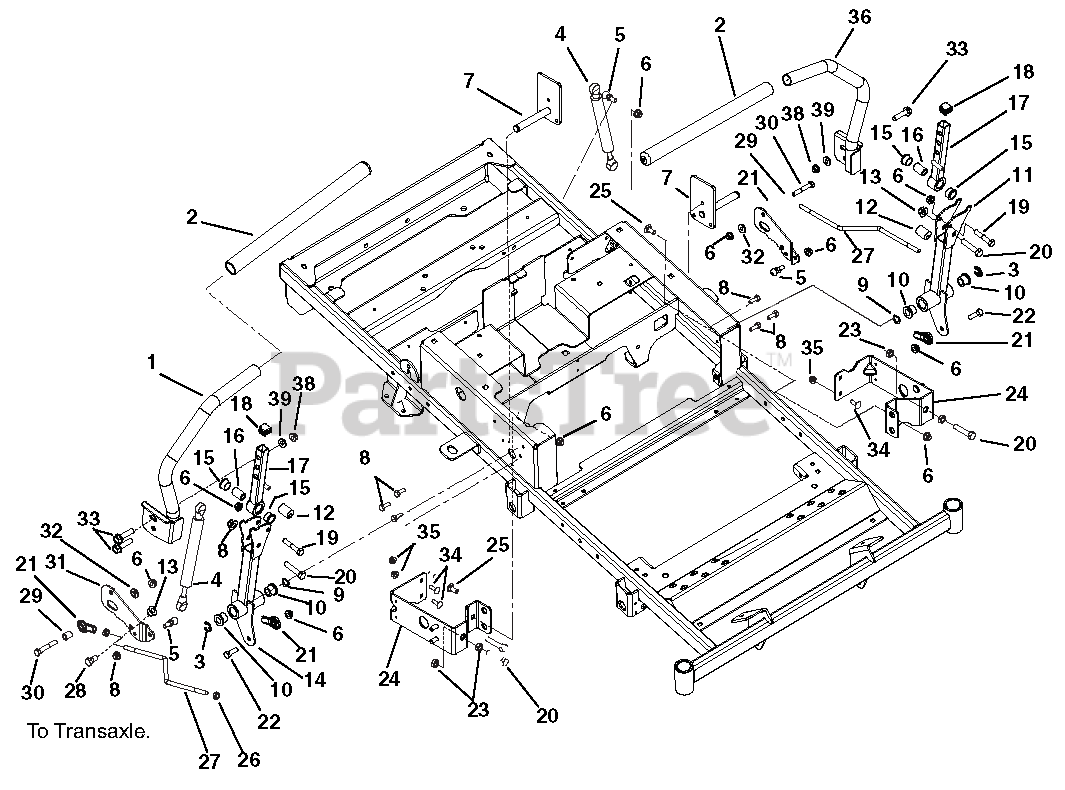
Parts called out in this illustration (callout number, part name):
1	WMT, STEERING HANDLE
2	GRIP, HANDLEBAR 15" FOAM
3	RG-RTNG-EXT .500X.042 (E)
4	DAMPER, STABILUS
5	STUD- BALL
6	@NUT-LK-NYL-FLG .31-18 YWZC
7	WMT, STEERING SHAFT
8	SCR-TAP .25-20X.50 HWH TR YWZ
9	WSHR-FL-STL 1.031X1.625X.188
10	BSHG-FLG .500X.750X.625X.937
11	WMT, LOWER CONTROL ARM
12	BSHG, ECCENTRIC .328X.750X.970
13	@NUT-LK-NYL-FLG .38-16 YWZC
14	WMT, LOWER CONTROL RH
15	BSHG-FLG, .625X.75X.450X.875
16	SPACER, .375X.625X.970 (PM)
17	WMT, UPPER CONTROL ARM
18	CAP PLUG, SQ 3/4-14-20 RIBBED
19	@BLT-HEX .31-18X1.75 GR5 YWZC
20	BLT-HEX .375-16X1.750 FTD YWZC
21	ALIGNABALL, 5/16 RH THREAD
22	@BLT-HEX .31-18X1.00 GR5 YWZC
23	NUT-HEX-JAM .375-16 YWZC
24	WMT, STEERING STOP
25	@BLT-RHDSSQNK .31-18X.75 G5YZ
26	NUT-JAM .31-24 YWZC
27	WIREFORM, STEERING LINK
28	@BLT-HEX .38-16X.75 GR5 YWZC
29	SPACER, .328X.500X.625
30	@BLT-HEX .31-18X2.00 GR5 YWZC
31	PLATE, DAMPER RH
32	BSHG-FLG .316X.430X.225X.750
33	BLT-SERHFWH .375-16X1.25 YWZC
34	@BLT-RDHDSQNK .25-20X.75 G5YZ
35	@NUT-LK-NYL-FLG .25-20 YWZC
36	WMT, STEERING HANDLE LH
37	PLATE, DAMPER (LH)
38	@NUT-LK-CTR-JAM .375-16 YWZC
39	@WSHR-FL-STL.406X.812X.065 YWZ
